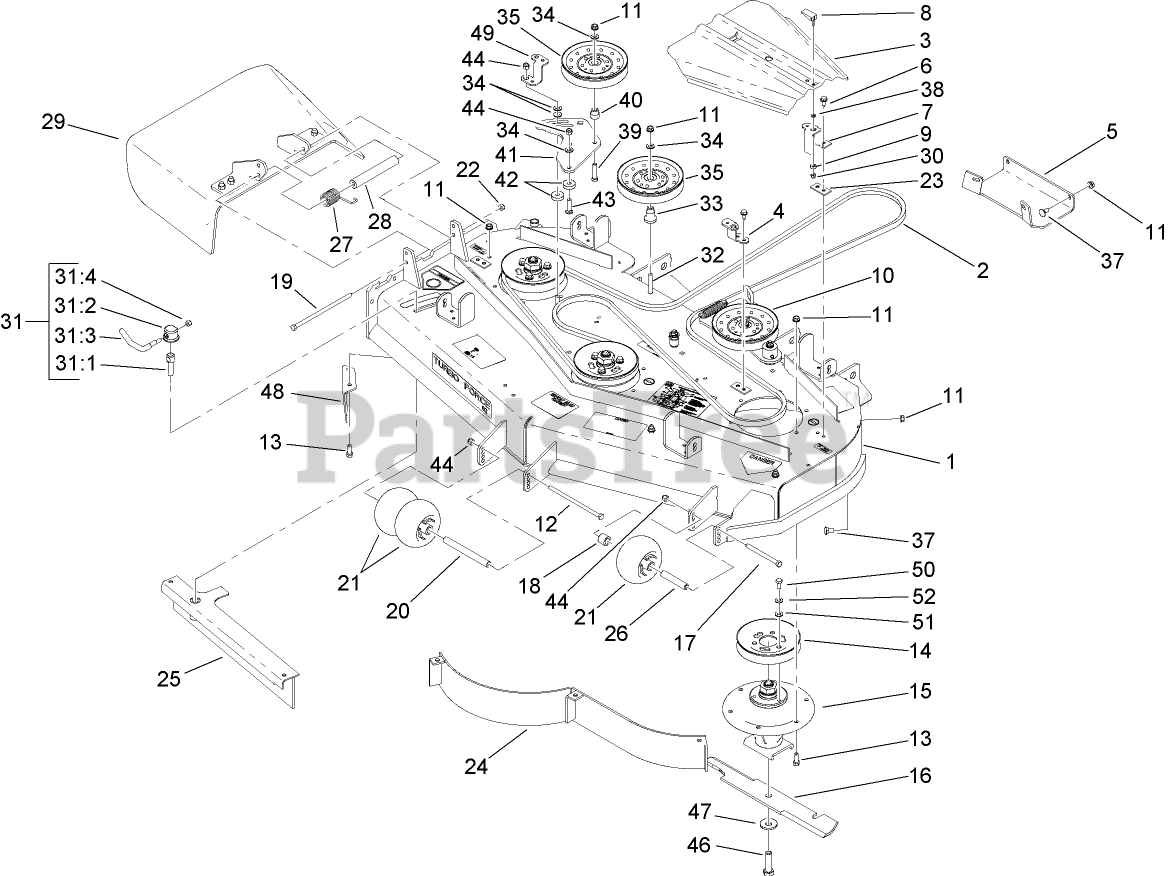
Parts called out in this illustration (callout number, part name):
1	DECK ASM
2	BELT-V
3	COVER-BELT
4	BRACKET-COVER, TALL
5	Plate-Skid
6	SCREW-HWHTF
7	BRACKET-COVER
8	HANDLE-LATCH, SWELL
9	BUSHING-LATCH, SWELL
10	SPRING IDLER ASM
11	NUT-HHF, WHIZ
12	SCREW-HH
13	SCREW-HWH
14	PULLEY
15	SPINDLE ASM
16	BLADE-18IN, HI FLOW
17	SCREW-HH
18	TUBE-SPACER
19	SCREW-HH
20	SPACER-WHEEL
21	ROLLER-SCALP, ANTI
22	NUT-LOCK, NI
23	SPACER-COVER, BELT
26	TUBE-SPANNER
27	SPRING-TORSION
28	SPACER
29	RUBBER DEFLECTOR ASM
30	NUT-LOCK, HH
31	LEVER ASM
31:1	Screw-Lock
31:2	CAP-LOCK
31:3	Lever-Lock
31:4	NUT-LOCK, NI
32	SCREW-CARR
33	MOUNT-PULLEY
34	WASHER-FLAT
35	Idler-Flat
37	SCREW-CARR
38	WASHER
39	SCREW-HH
40	BUSHING-IDLER
41	PLATE-IDLER
42	Spacer
43	SCREW-CARR
44	NUT-LOCK, NI
46	SCREW-BLADE
47	Washer-Blade Bolt, Heavy
48	BAFFLE-DISCHARGE
49	BRACKET-COVER, SHORT
50	SCREW-HH
51	WASHER-FLAT
52	WASHER-BELLEVILLE
